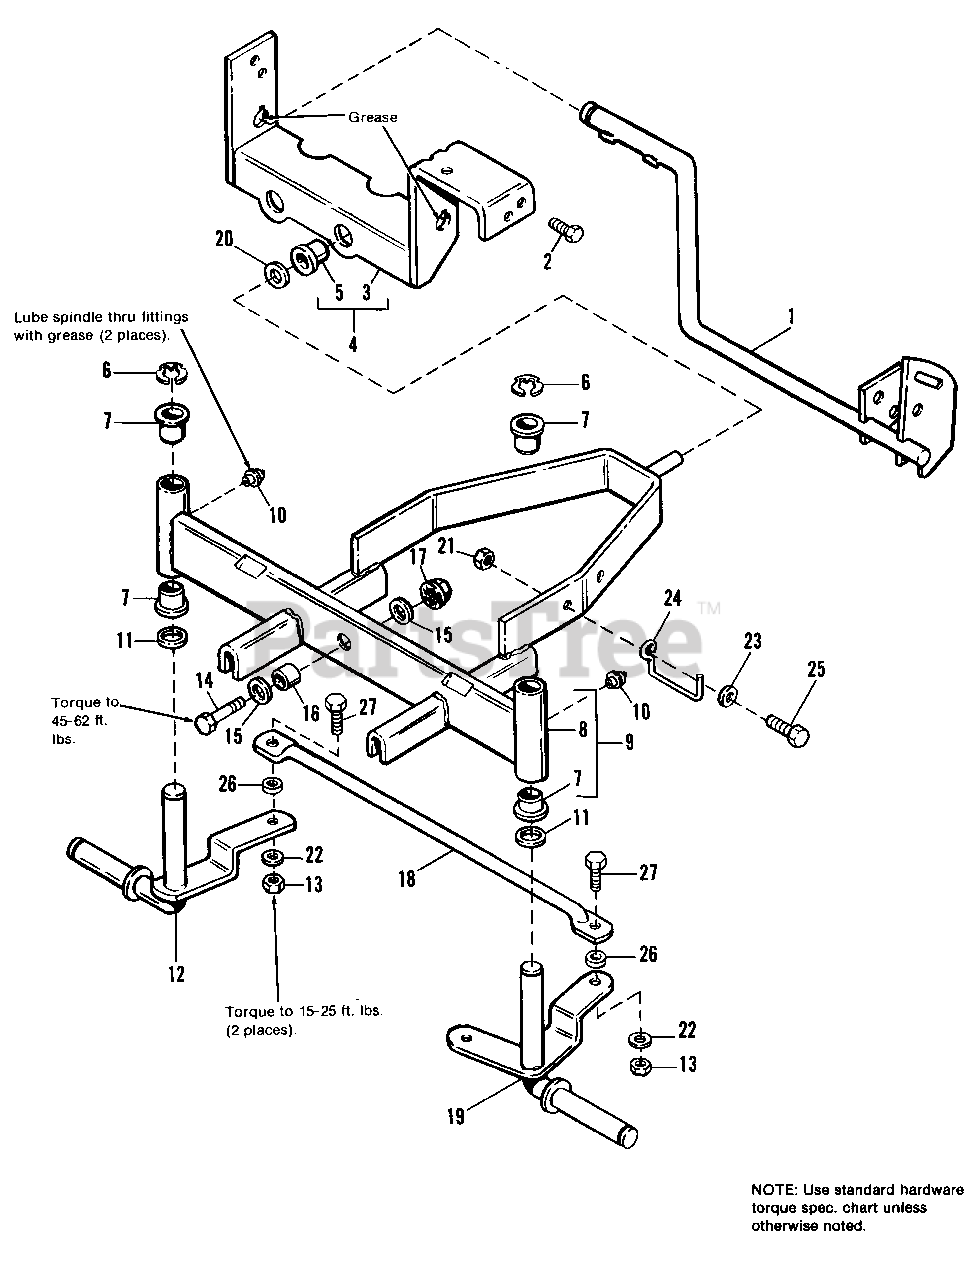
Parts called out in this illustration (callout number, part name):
1	LEVER ASSY., Brake
2	SCREW, Taptite, 5/16-18 x 3/4
4	SUPPORT ASSY., Rear w/Bushing (Includes Ref. No. 3 & 5)
6	"E" RING, Ext. 3/4
9	AXLE ASSY., Front (Includes Ref. No. 7 & 8)
10	FITTING, Lube, Drive Type
11	WASHER
12	SPINDLE ASSY. R.H.
13	LOCKNUT, Hex, 3/8-16
14	CAPSCREW, Hex, 1/2-13 x 1-3/4, Gr. 8
15	WASHER, 17/32
16	SPACER
17	NUT, Hex Flangelock, 1/2-13
18	TlE ROD ASSY.
19	SPINDLE ASSY., L.H.
20	WASHER, 21/32
21	NUT, Hex, 5/16-18
22	WASHER, 3/8
23	WASHER, 11/32
24	GUIDE, Drag Link
25	CAPSCREW, Hex Hd., 5/16-18 x 1
26	SPACER, Spindle
27	CAPSCREW, 3/8-16 x 1
